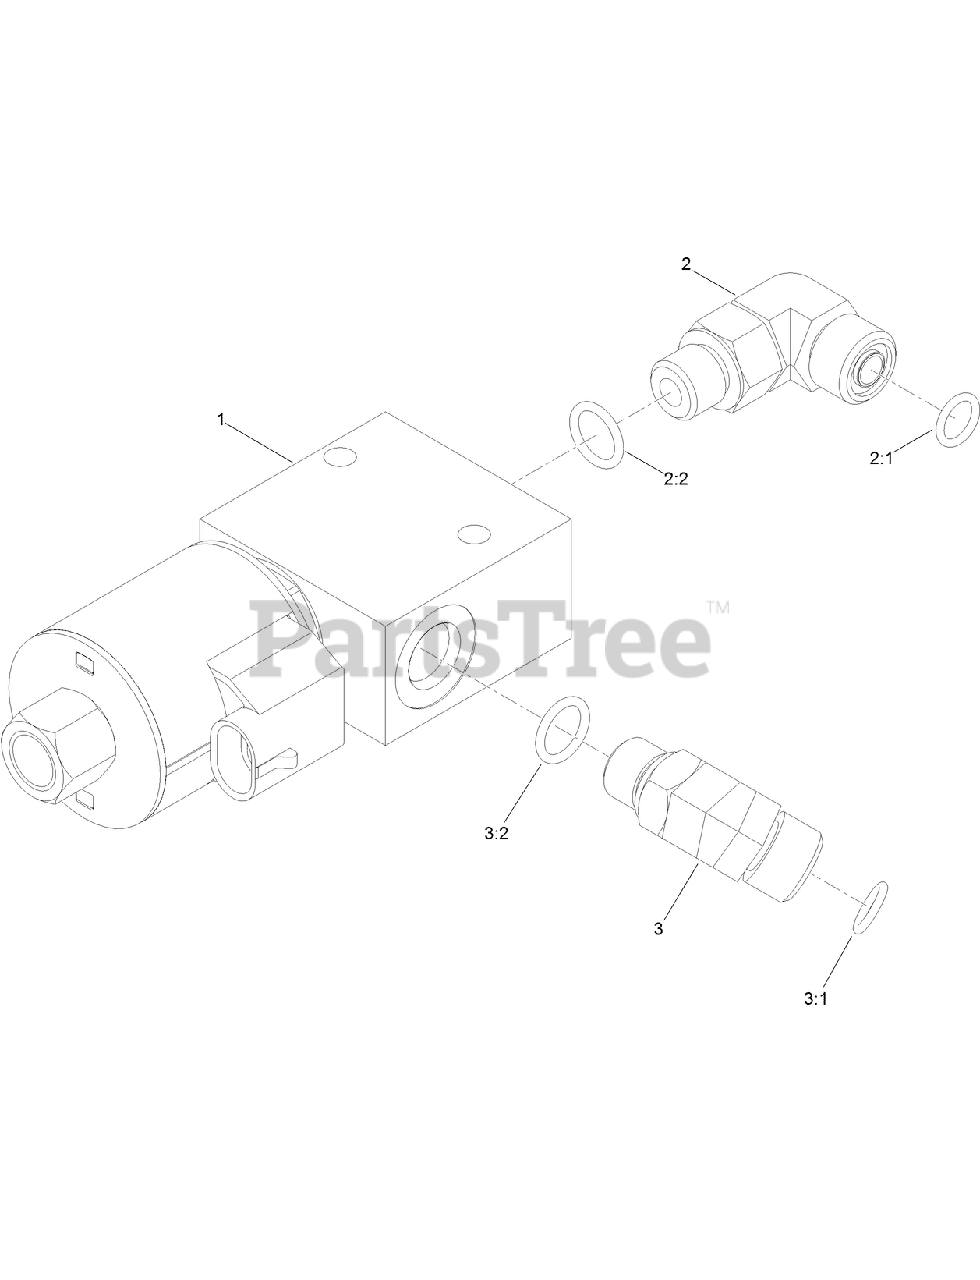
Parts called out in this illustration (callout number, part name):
1	MANIFOLD-RELIEF, PROPORTIONAL
2	FITTING-ELBOW, 90 DEG
2:1	O-RING
2:2	O-RING
3	FITTING-ELBOW, 45 DEG
3:1	O-RING
3:2	O-RING
